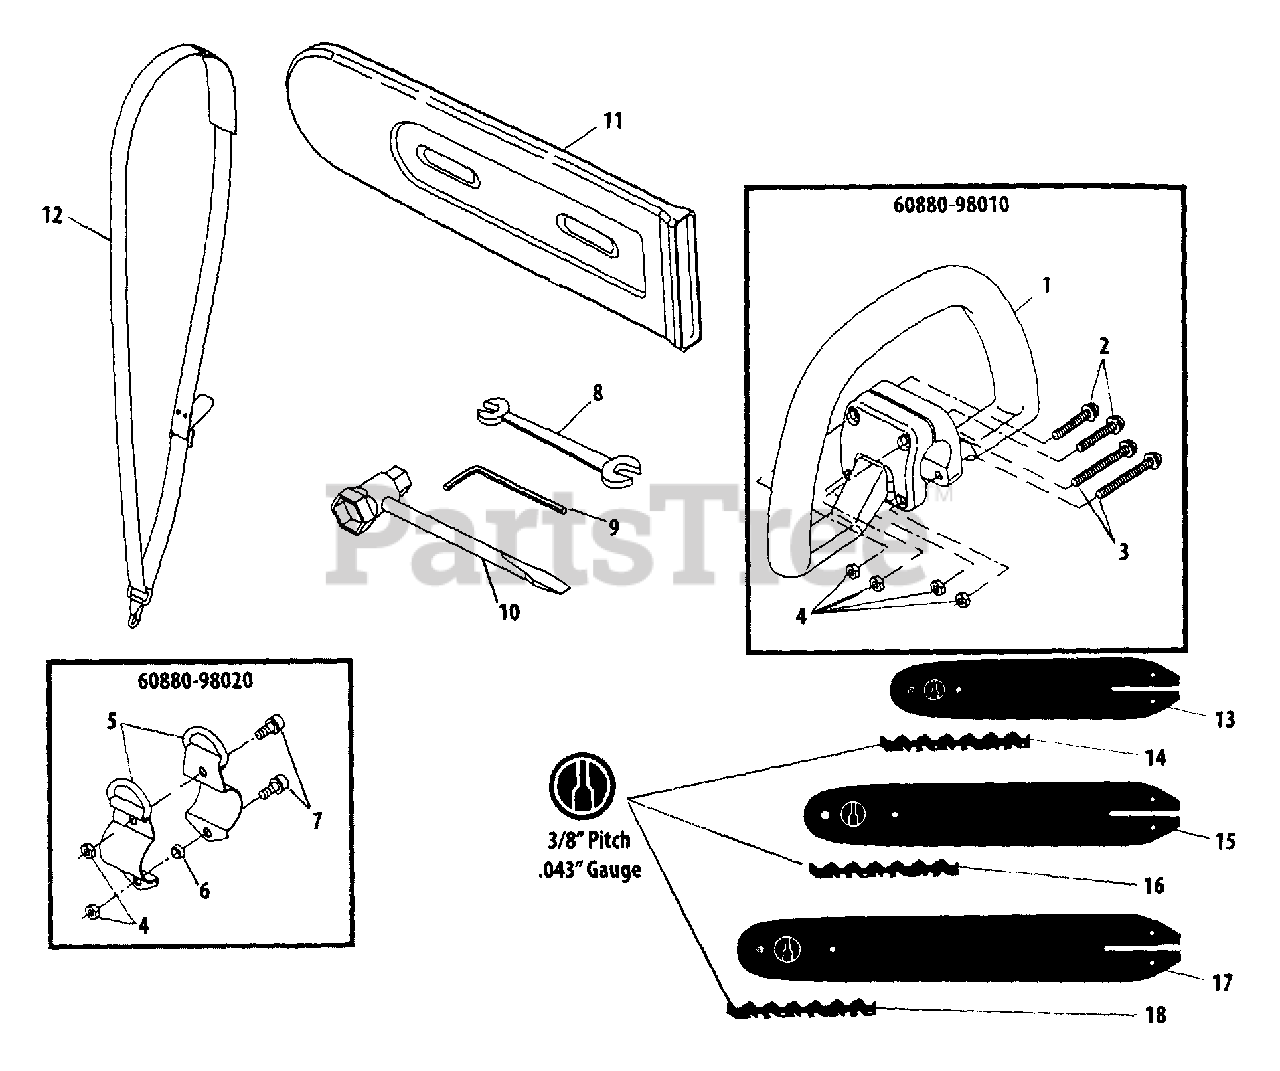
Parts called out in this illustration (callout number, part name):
2	SCREW M5×30
3	SCREW - 5×45
4	NUT M5
5	HANGER SET
7	BOLT M5×12
8	SPANNER 8×10
9	WRENCH, ALLEN 4 MM
10	T-WRENCH
11	SCABBARD
12	STRAP ASSY
13	GUIDE BAR - 8"
14	SAW CHAIN 8"
15	GUIDE BAR - 10"
16	SAW CHAIN 10"
18	SAW CHAIN 12"
60880-98010	HANDLE ASSY
60880-98020	HANGER ASSY
